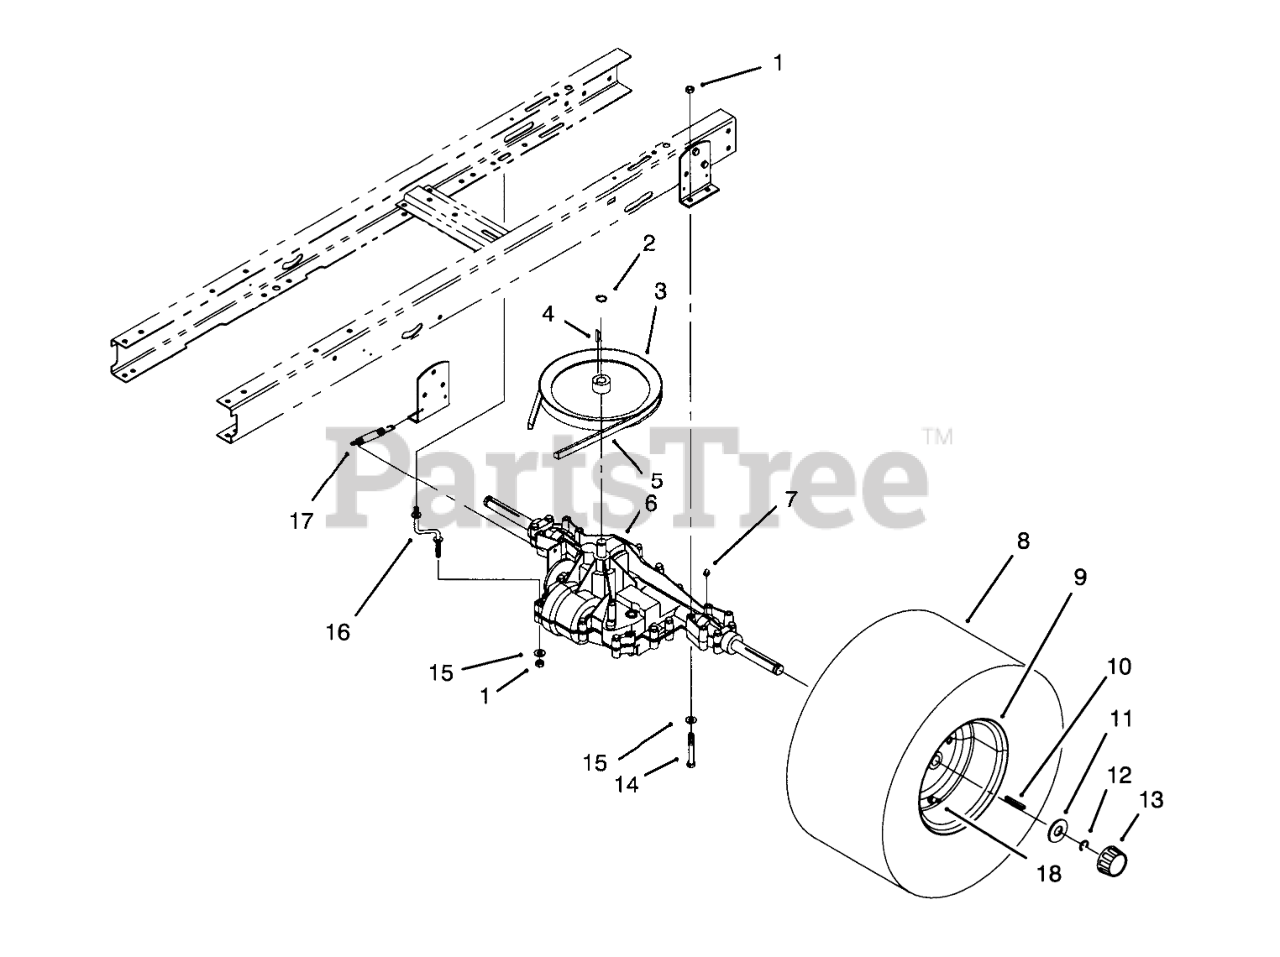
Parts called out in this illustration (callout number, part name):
1	NUT-LOCK, NI
2	RING-SNAP, EXTERNAL
3	PULLEY-TRANSMISSION
4	KEY-WOODRUFF
5	V-BELT
6	Transaxle
7	FITTING-LUBE, 45 DEG
8	TIRE 18 X 9.50 X 8
10	KEY-SQUARE
11	WASHER-PLAIN
12	E-RING
13	CAP-HUB
14	SCREW-HH
15	WASHER-PLAIN
16	TORQUE STRAP
17	SPRING-RETURN, BRAKE
18	STEM-VALVE
